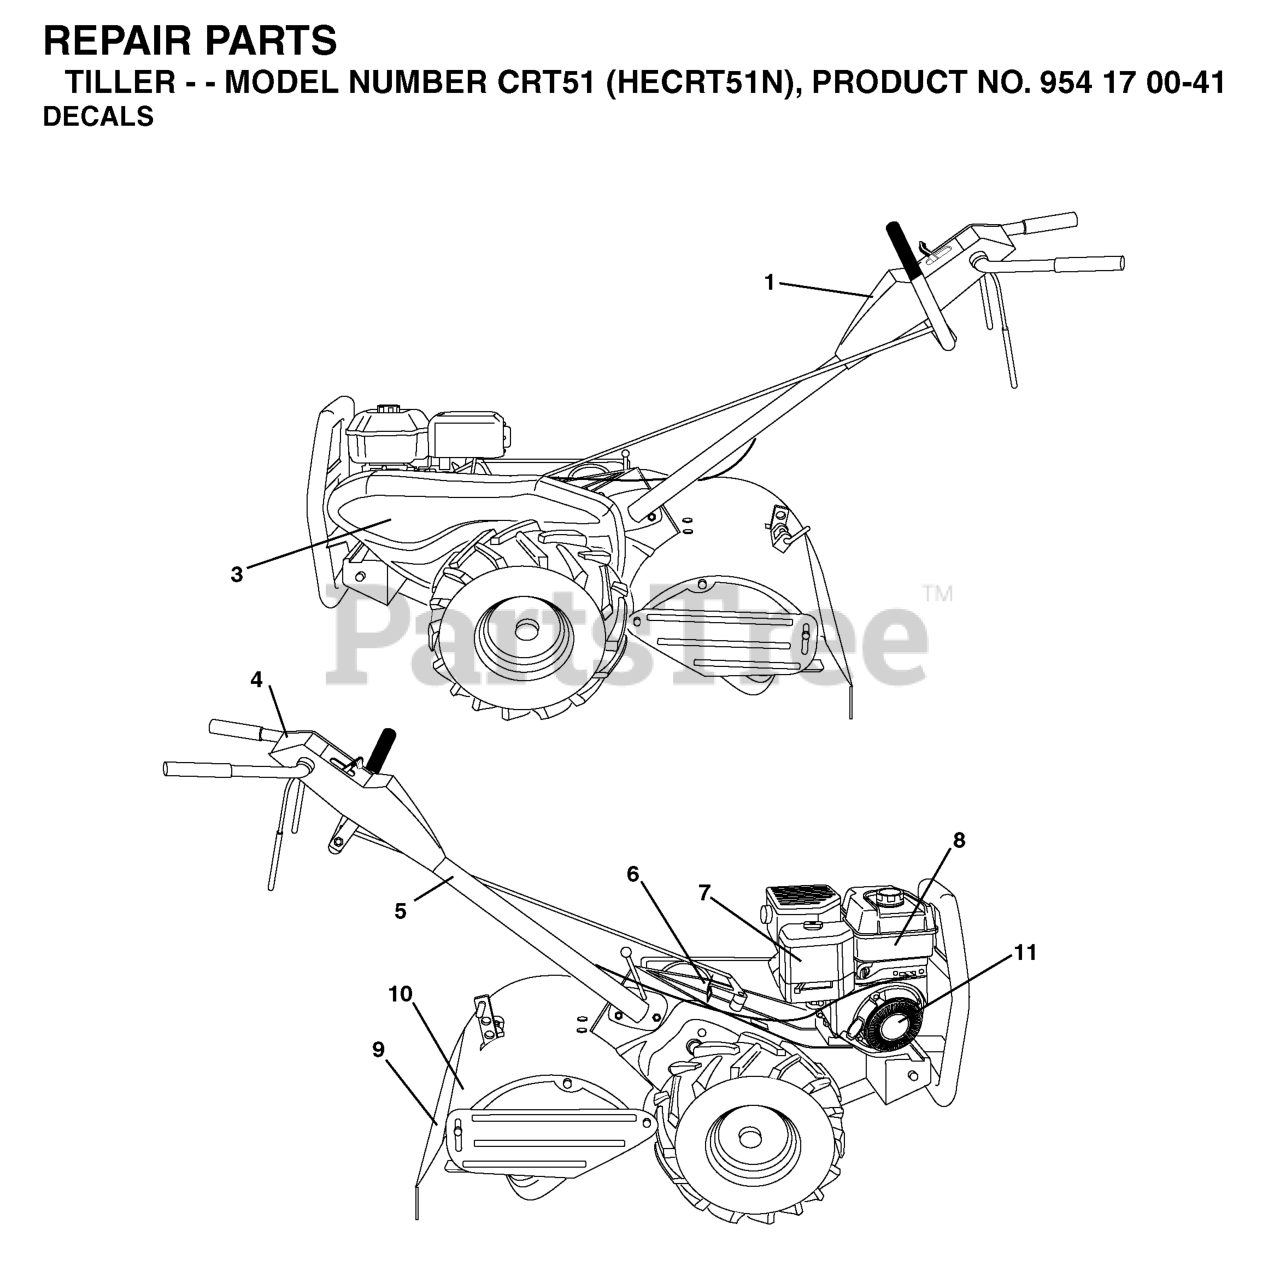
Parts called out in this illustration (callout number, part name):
1	DECAL,HUSQVARNA,CONTROL PANEL
3	DECAL.BELT.GUARD.HUSQ.TILLER
5	DECAL.PLACEMENT.HAND.SYMBOLS
6	DECAL.SHIFT.INDICATOR.TILLER
8	DECAL, ENGINE INTEK REF
9	DECAL.WARNING.4-SYM.TILLER.INT
10	DECAL EUROPE STANDARD CE
11	DECAL.REWIND
